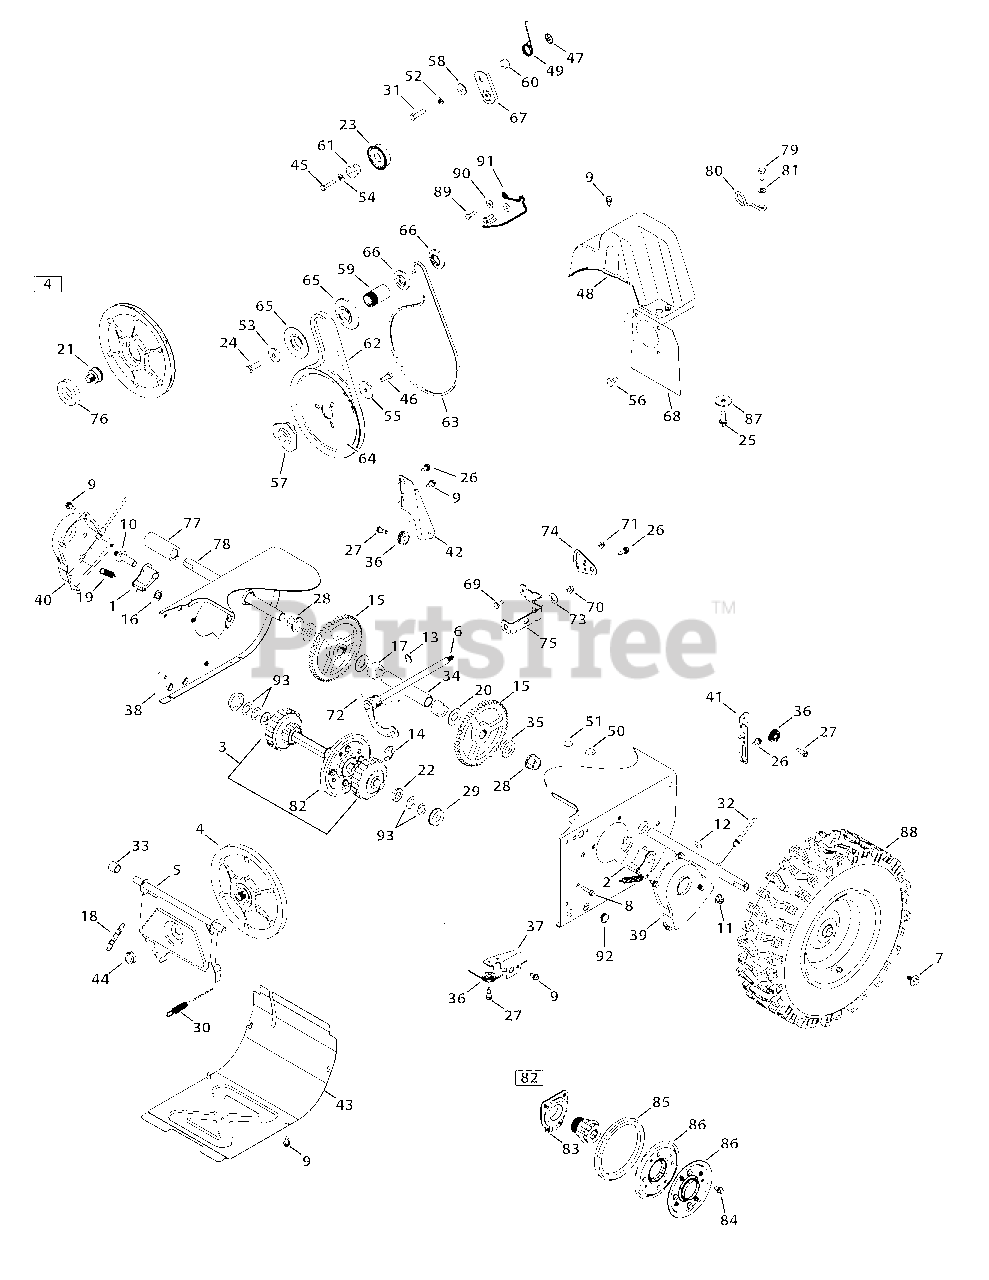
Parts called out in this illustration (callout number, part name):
1	Dogg Assembly, RH
2	Dogg Assembly, LH
3	Drive Shaft Assembly
4	Friction Wheel Disc Assembly
5	Friction Wheel Support
6	Rod Shift Assembly
7	Screw, 5/16-24 x .750
8	Screw, 1/4-20 x 1.000
9	Screw, 1/4-20 x .625
10	Actuator Shaft
11	Nut, Flangelock, 3/8-16
12	Hi-Pro Key, 3/16 x 3/4 DIA
14	Retainer Ring
16	Nut, Speed, .500
17	Spacer, .76 x .75
18	Extension Spring, .380 x 2.500
19	Extension Spring, .500 x 1.71
20	Washer, Flat, .76 x 1.49
21	Friction Pin, Disc Bearing
22	Spacer, .68 ID x 1.25 OD x .20
23	Pulley Assembly
24	Hex Head Screw, 3/8-24 x 1.25
25	Taptite Sems Screw, 3/8-16 x 1.000
26	Screw, Shoulder, .368 x .113 x 1/4-20
27	C Screw, Shoulder, .340 x .335 x 1/4-28
28	Hex Flange Bearing, .75 ID
29	Ball Bearing, 17 x 40 x 12
30	Drive Clutch Cable
31	Hex Head Screw, 5/16-24 x 1.25
32	Steering Cable
33	Spacer, .508 x .75
34	Axle Support Tube
35	Spacer, Axle
36	Roller Cable
37	Auger Cable Guide Bracket
38	Wheel Drive Frame
39	Shaft Retainer, LH
40	Shaft Retainer, RH
41	Auger Clutch Cable Guide Bracket
42	Drive Clutch Cable Guide Bracket
44	Nut, Flange, 5/8-18
45	Taptite Screw, 1/4-20 x 1.250
46	Hex Head Screw, 5/16-24 x .875
47	Nut, Push-On, .25 DIA
48	Belt Cover
49	Spring, Torsion, .850 x .333
50	Plug, 3/8 ID
51	Plug, 1/2 ID
52	Washer, Lock, 5/16
53	Washer, Flat, .45 x 1.5
54	Washer, Lock, 1/4
55	Washer, Flat, .34 x 1.50
56	Screw, Shoulder
57	Pulley Adapter, .75 DIA
58	Spacer, Shoulder, .3175 x .500
59	Spacer, .875 x 1.185
60	Spacer, .340 x .750
61	Spacer, Shoulder, .260 x .785
62	Belt, .500 x 37.00
63	V Belt, 3/8 x 35.68"
64	Auger Pulley, 8.1 x .5
65	Pulley, Half, 4L-V x 2.600
66	Pulley, Half, 3/8-V x 1.7160
67	Drive Idler Bracket
68	Cover Plate
69	Hex Head Screw, 1/4-20 x .620
70	Nut, Flangelock, 5/16-18
71	Nut, Flangelock, 1/4-20
72	Spring, Torsion, .750 x .968
73	Washer, Flat, .469 x .875 x .105
74	Speed Selector Pivot Bracket
75	Speed Selector Shift Bracket
76	Ball Bearing, 30 x 55 x 13
77	Spacer, 1.25 x .75 x 3.00
78	Axle, .75 x 11.12
79	Hex Head Screw, 1.25 x 20
80	Cable Guide
81	Washer, Flat, .330 x .630
82	Friction Wheel Assembly
83	Bearing Assembly, Friction Wheel
84	Screw, 5/16-18 x .750
85	Friction Wheel, 5.5 OD
86	Friction Wheel Plate
87	Washer, Flat, .38 x 1.38
88	Wheel, LH, 16 x 6.5-8
88	Wheel, RH, 16 x 6.5-8
89	Hex Head Screw, 5/16-24 x 1.00
90	Washer, Flat, .349 x .879
91	Belt Guide
92	Plug, 5/8 Hole
93	Flat Washer, .67 x 1.174 x .02
